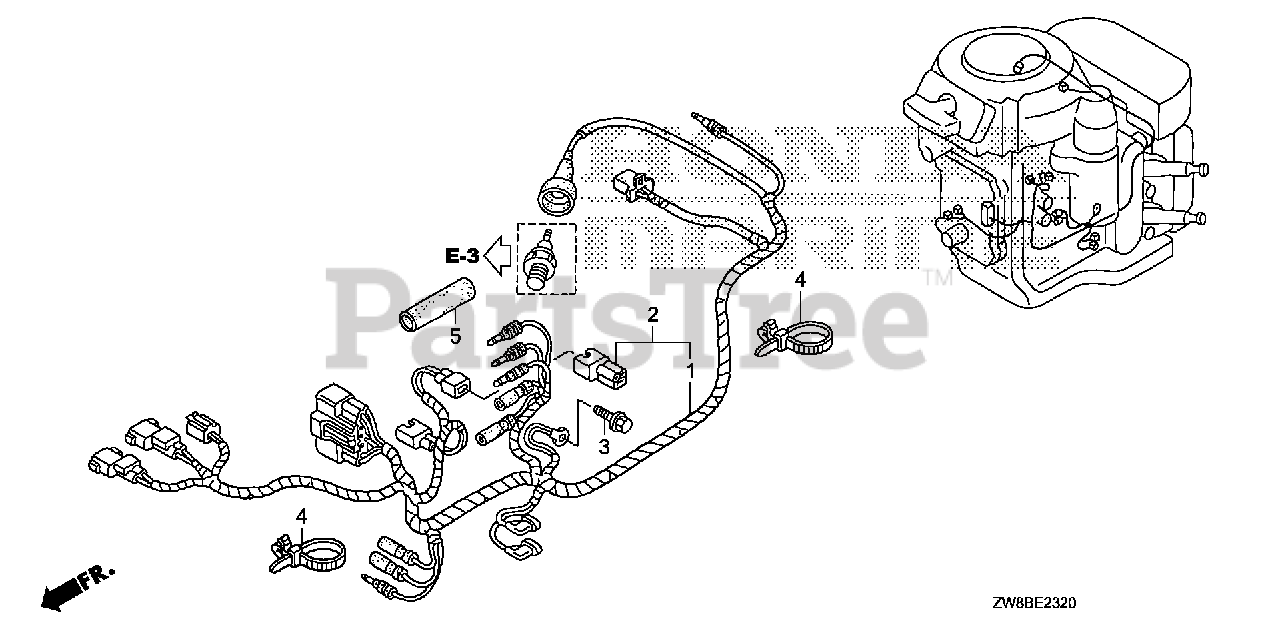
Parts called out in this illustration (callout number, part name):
1	WIRE HARNESS ASSY. (R/C)
3	BOLT, FLANGE (6X12)
4	BAND, WIRE (95MM)
5	TUBE, RUBBER (11.5X14.5)
